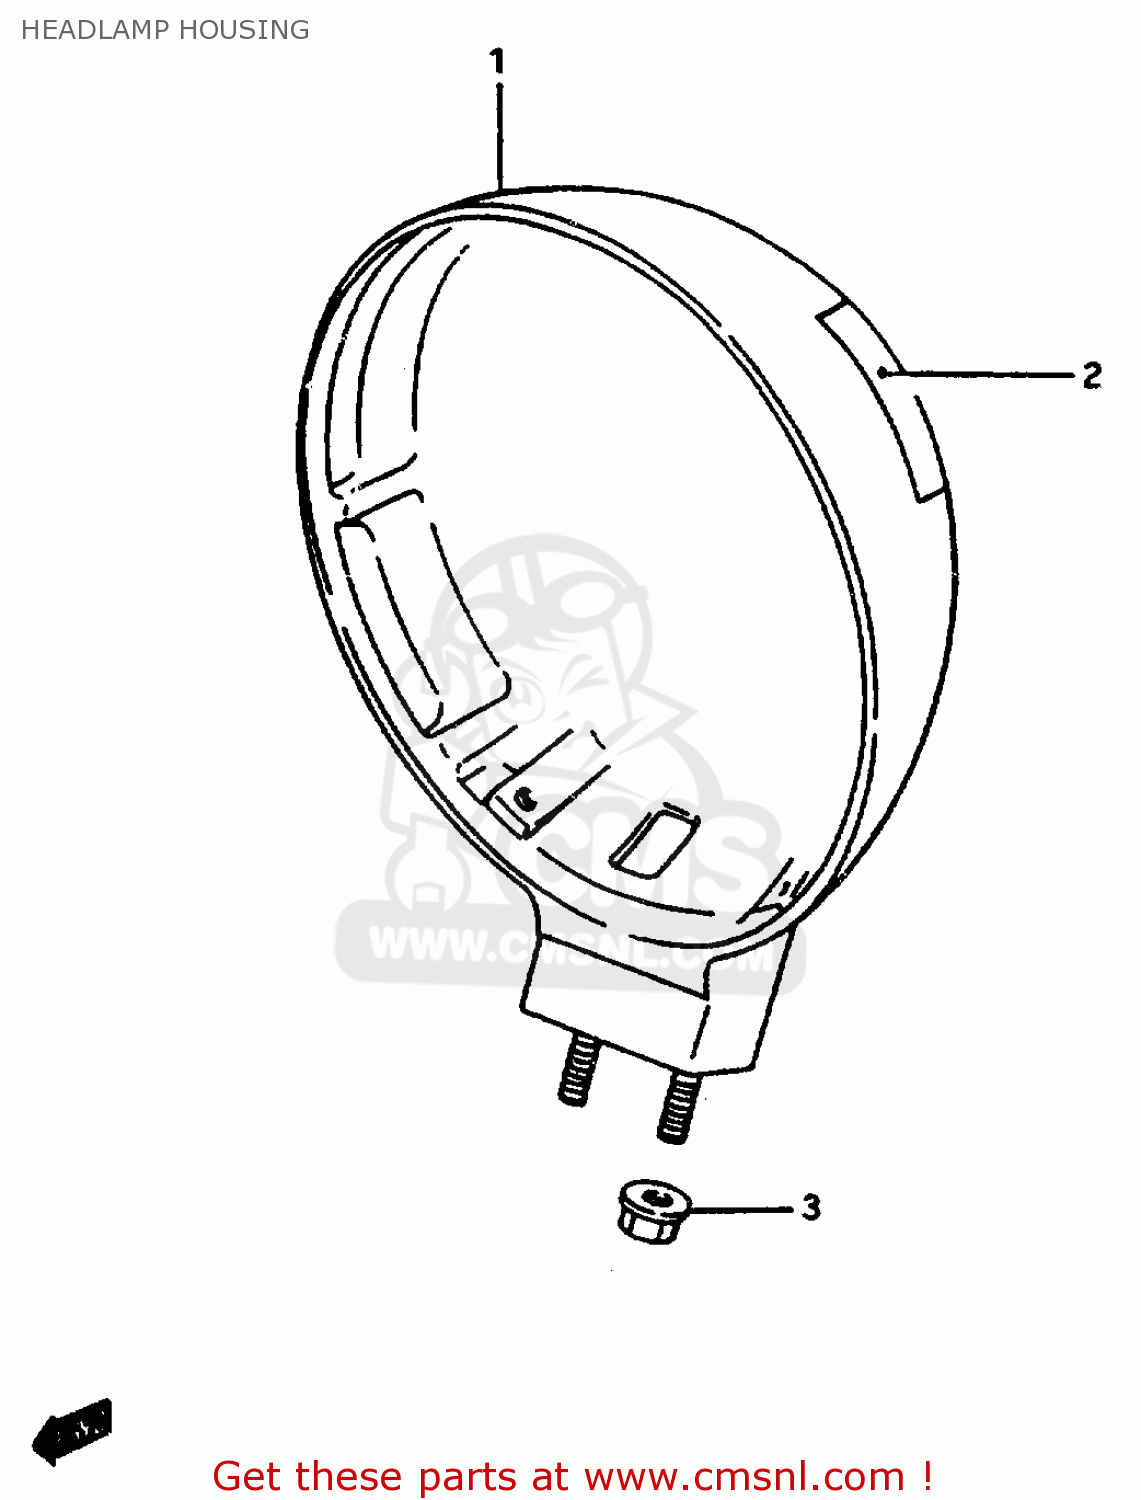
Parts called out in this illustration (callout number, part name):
1	HOUSING,HEADLAMP
2	TAPE,FRAME HEAD COVER
3	NUT
